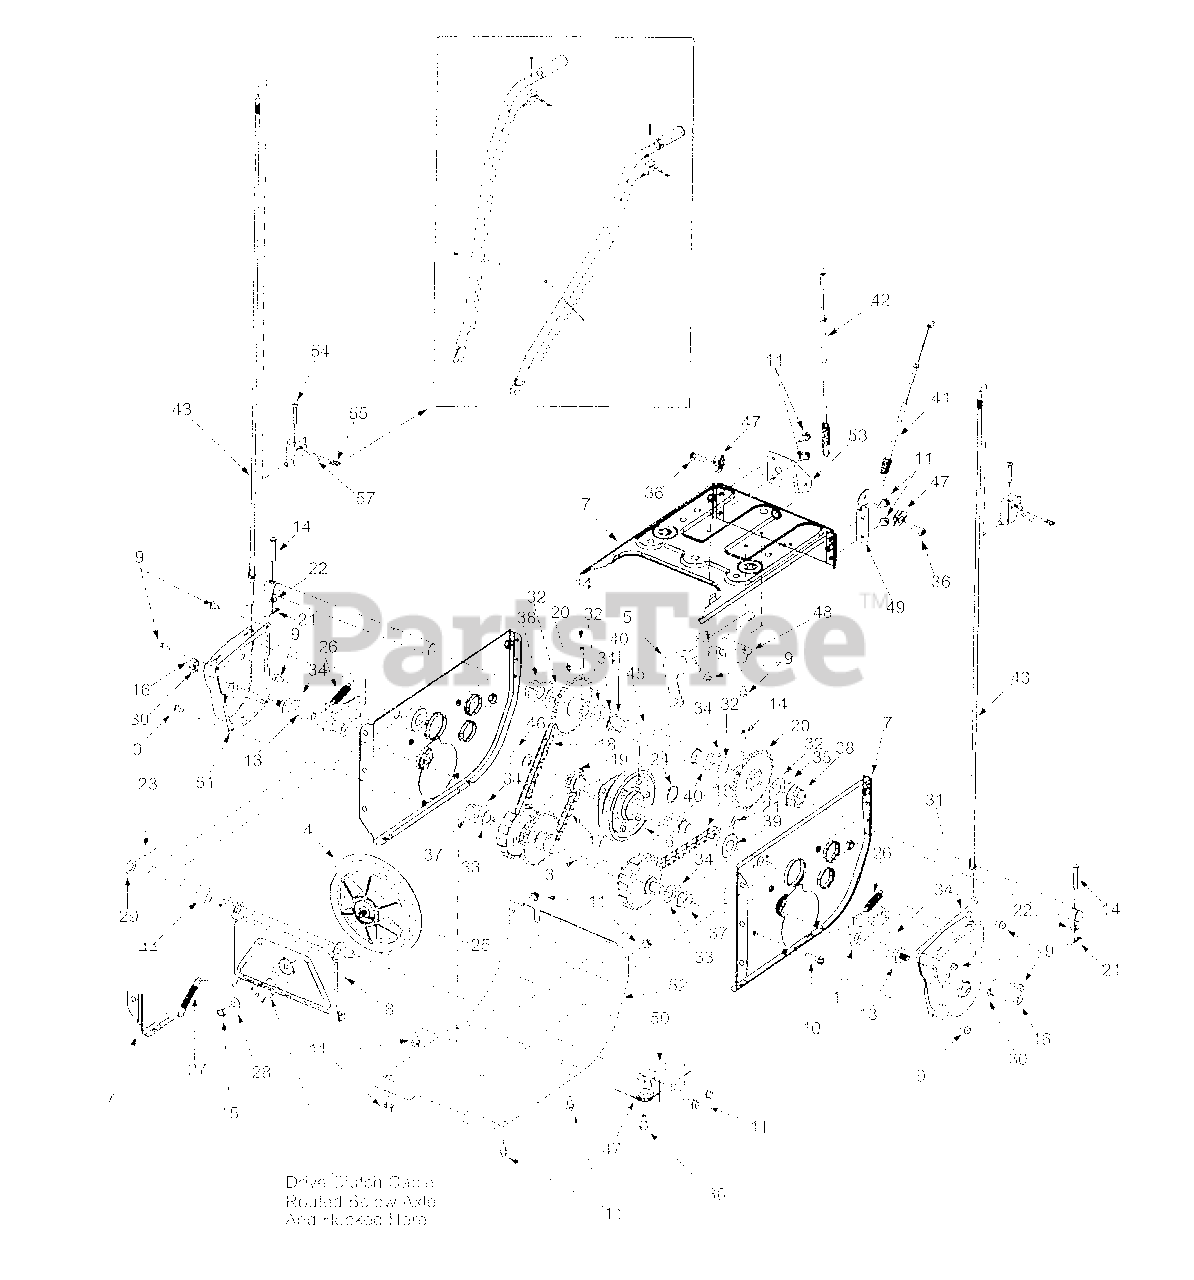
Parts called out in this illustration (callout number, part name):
1	Dogg Assembly: RH
2	Dogg Assembly: LH
3	Shift Assembly: Steerable Drive
4	Friction Wheel Disc Assy.
6	Wheel Assembly, Friction
9	Hex Washer Screw 1/4-20 x.5
10	Hex Washer Screw 1/4-20 x 1
11	Hex Screw 1/4-20 x .625"
12	Drive Shaft
13	Actuator Shaft
15	Jam Nut 3/8-24 Gr.8
16	Hex Nut: 3/8-16
19	Sprocket: 10T
21	Cotter Pin
22	Flat Washer
23	Cotter Pin
24	Snap Ring
25	Adhesive: Loctite
26	Extension Spring
27	Extension Spring
28	Bell Washer
29	Flat Washer
30	Lock Washer
33	Flat Washer
34	Lubricant: 6 in 1
35	Grease
36	Shoulder Screw
37	Hex Flange Bearing
38	Hex Flange Bearing
39	Ball Bearing
40	Flange Bushing
41	Auger Clutch Cable
42	Drive Clutch Cable
43	Steering Cable
45	Axle Support Tube
47	Roller Cable
56	Cable Tie
57	Turn Trigger
58	Cotter Pin
